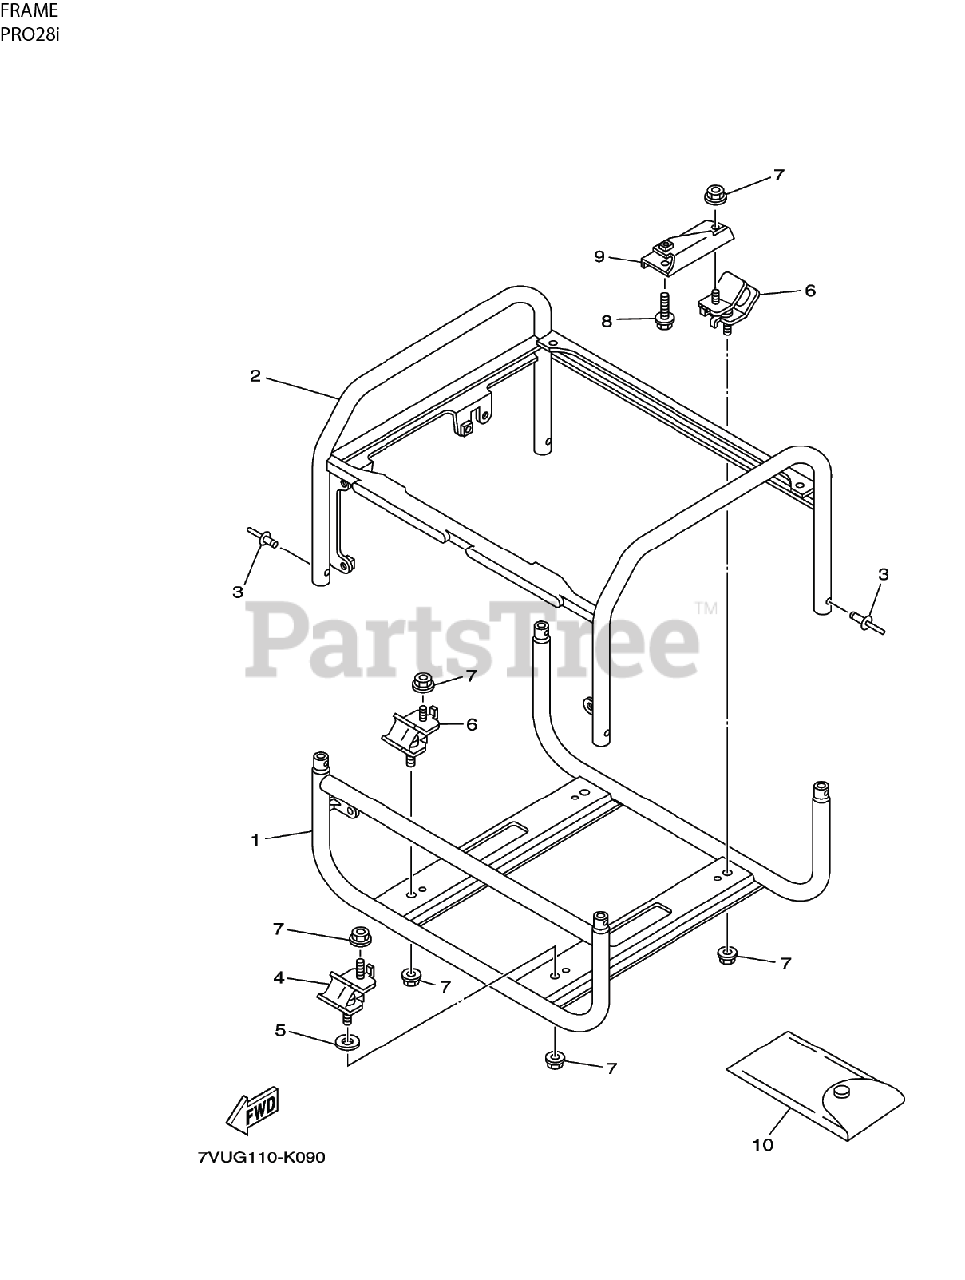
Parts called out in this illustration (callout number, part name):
3	RIVET, BLIND
4	MOUNT, INSULATOR
5	WASHER, PLATE
6	MOUNT, INSULATOR
7	NUT, FLANGE
8	SCREW - BOLT FLANGE
9	BRACKET, ENGINE
10	WASHER, PLATE
